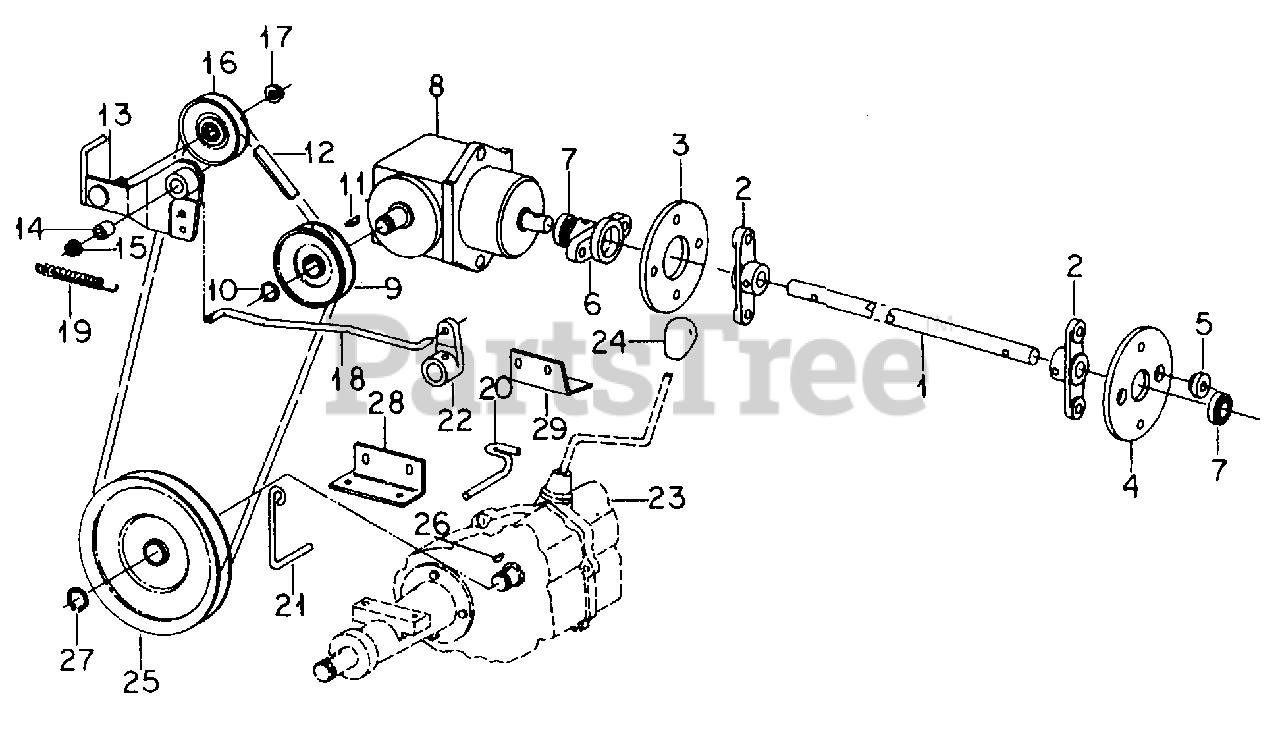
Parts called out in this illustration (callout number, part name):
1	Shaft, Drive
2	Arm, Coupling
3	Disc, Flexible Coupling
4	Disc, Flexible Coupling
6	Coupler, Driveshaft
7	Bushing, Self Aligning Ball
8	Drive, Right Angle
9	Pulley, Drive
10	Ring, Retaining
11	Key, 3/16 X 3/4 Woodruff 9
12	Belt, Clutching
13	Arm Assy, Clutch
14	Bushing, Clutch Arm
15	Nut, 5/16 Flange Lock
16	Pulley, Drive Idler
17	Nut, 3/8 Flange Lock
18	Rod, Clutch
19	Spring, Clutch
20	Guide, Belt
21	Guide, Belt
22	Lever, Neutral Return
23	Transaxle
24	Knob, Shifter
25	Pulley, Transaxle
26	Key, 3/16 X 3/4 Woodruff 9
27	Ring, Ret.
28	Bracket, Trans Mtg
29	Bracket, Trans, LH
